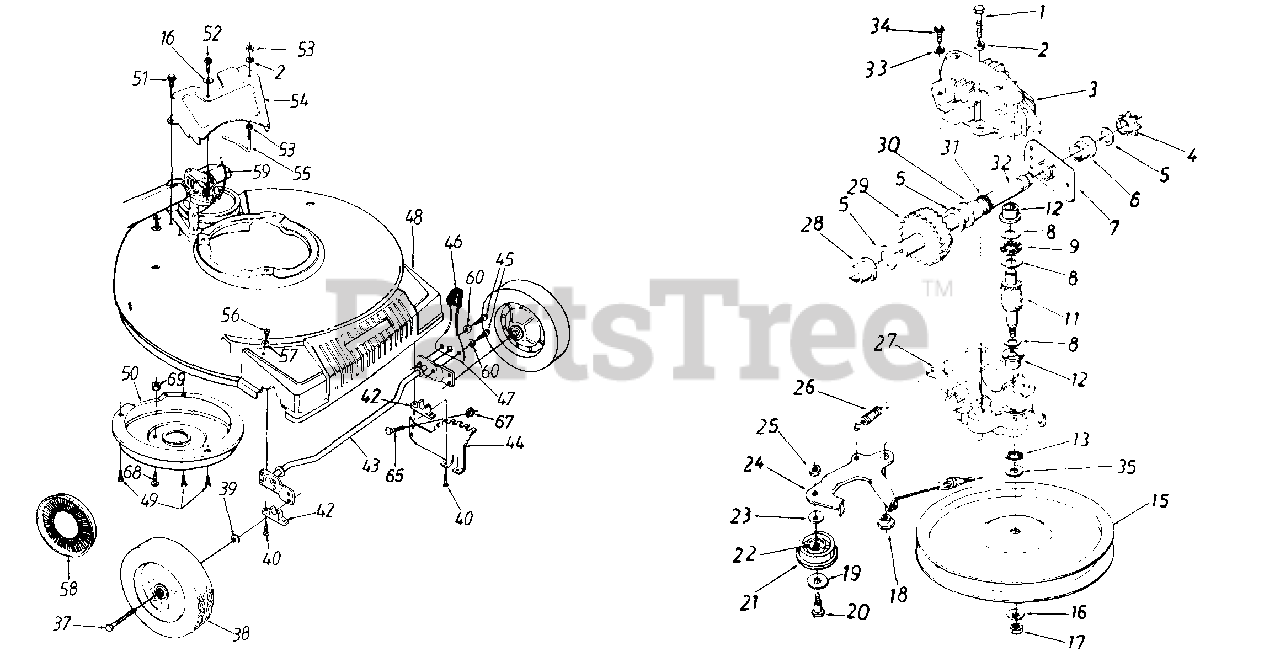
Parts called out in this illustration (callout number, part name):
1	Hex Patch Bolt 1/4-20 x 1.25"
2	L-Wash. 1/4" I.D.
3	Upper Hsg. Half
4	#48 Sprocket 7T x 1/2 Pitch
5	Fl-Wash. 5/8" I.D. x .030
6	Hex Flange Brg..631" I.D.
8	Thrust Wash..382" I.D. x .70" O.D.
9	Thrust Bearing .3/5" I.D. x .812" O.D.
11	11 Tooth Pinion Shaft
12	Flange Bearing
13	Oil Seal
15	Fl-Pulley 5.06" O.D.
16	Bell-Wash..265" l.D. x .75"
17	Hex L-Nut 1/4-28 L.W. Thd.
18	Shld. Spacer .375" Dia. x .170
19	Fl-Wash..390" l.D. x 1.0"
20	Shld. Bolt .375" Dia. x .40"
21	Fl-Idler Plastic 1.50" Dia.
22	Needle Brg..375" x .31
24	Idler Brkt. Ass'y.
25	Hex Patch L-Nut 1/4-28 Thd.
26	Extension Spring 1.12" Lg.
27	Lower Hsg. Half
28	Flange Bearing .566 Dia.
29	33 Tooth Helical Gear
30	Flange Bearing .629 Dia.
31	Oil Seal .625 Dia.
32	Gear Sprocket Shaft
33	L-Wash. #10 I.D.
34	Hex B-Tap Scr. #10 x .62"
35	Wex Washer .26" x .88"
37	Front Axle Bolt
38	Wheel Ass'y. Comp.
39	Bell-Wash..380" I.D. x .88
40	Hex Wash. Hd. Scr. 1/4 x 1" Lg.
42	Block Bushing
46	Knob
47	Spring Lever
48	Plastic Front End
49	Hex B-Tap Scr. 1/4" x .38"
52	Hex Wash. Hd. B-Tap Scr. 1/4 x .62"
53	Hex Nut 1/4-20 Thd.
56	Ton Truss Hd. Scr. 5/16 x .75" Lg.
57	Bell-Wash..345" I.D. x .88"
58	Hub Cap
59	S.P. Cable 44" Lg.
60	External L-Wash. 1/4" I.D.
65	Carr. Bolt 1/4-20 x .5" Lg.
67	Hex Flange L-Nut 1/4 -20 Thd.
68	Pan Hd. Scr. 1/4-20 x 2" Lg.
69	Hex L-Nut 1/4-20 Thd.
